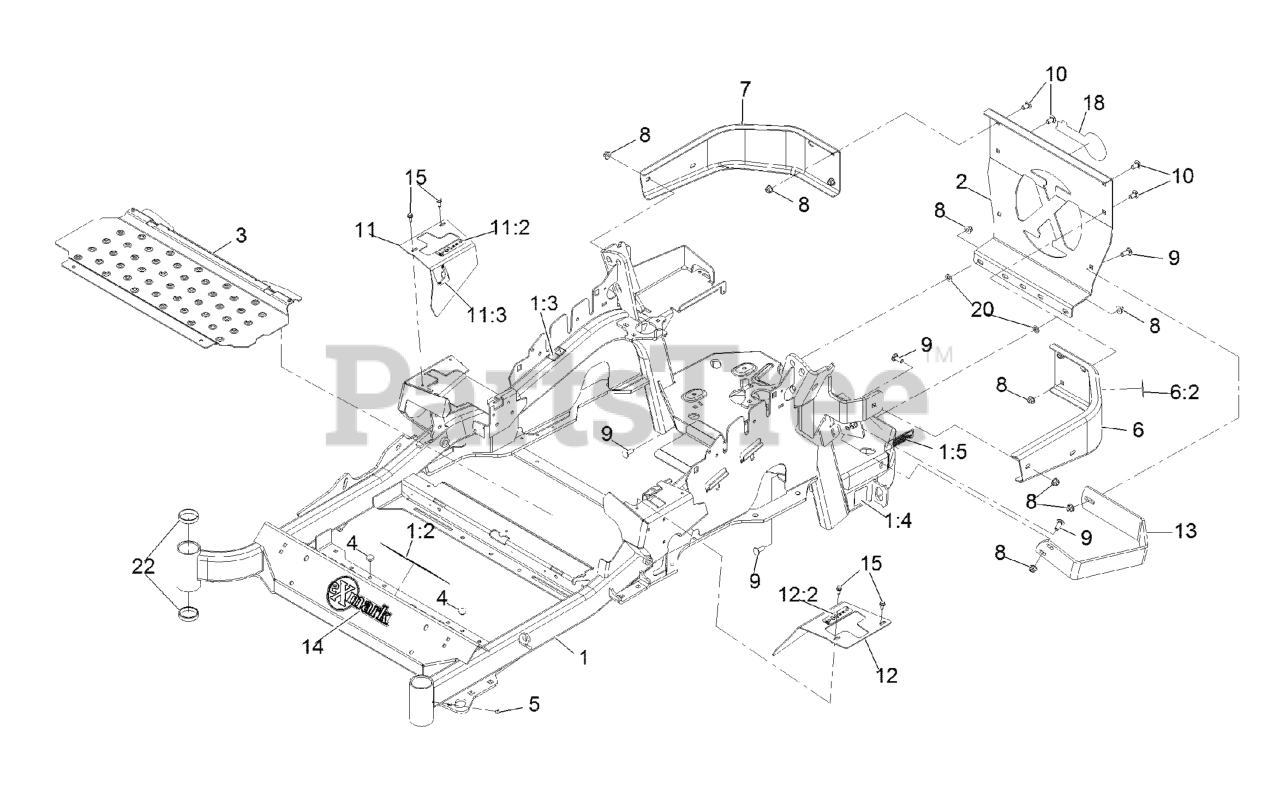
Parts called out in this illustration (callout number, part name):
1	MAINFRAME ASM
1:2	DECAL-DANGER
1:3	DECAL-WARNING
1:4	DECAL-HAZARD, PINCHED FINGER
1:5	DECAL-SPARK ARRESTER
2	PLATE,REAR GUARD
6	LH BUMPER ASM
6:2	DECAL-WARNING
7	BUMPER-RH
8	NUT-HF, NI
9	SCREW-CARR
10	SCREW-CARR
11	RH MOTION CONTROL COVER ASM
11:2	DECAL-CONTROL, MOTION
11:3	DECAL-PARK BRAKE, CE
12	LH MOTION CONTROL COVER ASM
12:2	DECAL-CONTROL, MOTION
13	GUARD-MUFFLER
14	DECAL-EXMARK LOGO
15	SCREW-HWH
18	DECAL-EXMARK LOGO
19	Decal-Patent Ttco.Com
20	NUT-PUSH
21	DECAL-FUEL FILL, CE
22	CUP-BEARING
24	BOLT-CARR
